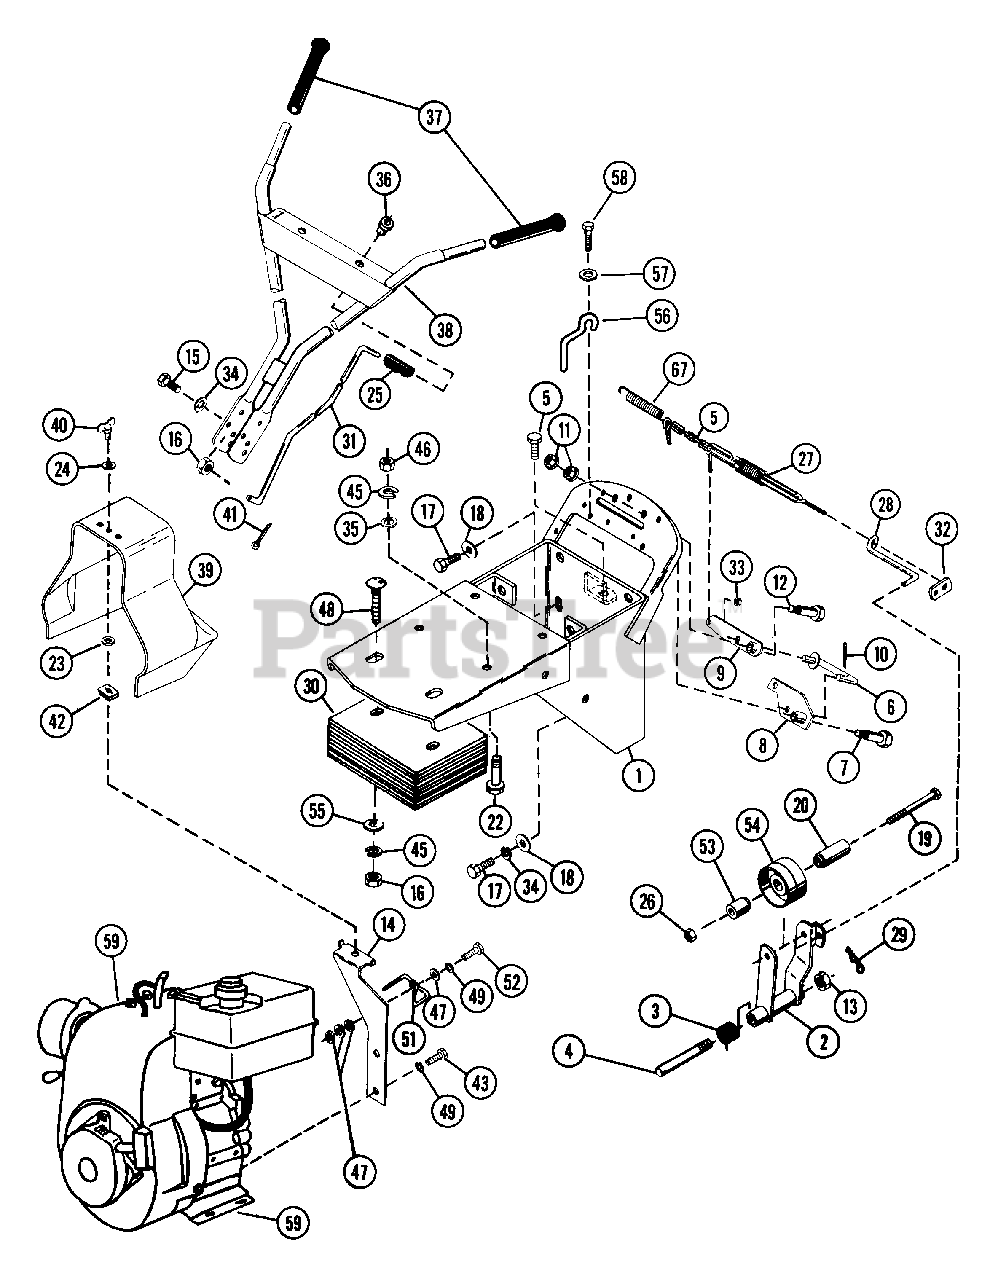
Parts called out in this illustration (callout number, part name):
2	IDLER ARM
3	SG-TORS .076X.89X1.98
4	IDLER PIN
5	BLT-HEX .31-18X1.00 PL GR 2
6	CLUTCH LINK
7	SHOULDER BOLT
8	CLUTCH BELLCRANK
9	SPRING ARM
10	PIN-COTR .09X1.0 PL
11	NUT-LK-CTR .375-16 GR A PL
12	SHOULDER BOLT
13	NUT-LK-FLG .375-16 PL
14	BELT COVER BRACKET
15	BLT-HEX .38-16X1.00 PL
16	NUT-HEX .375-16
17	BLT-HEX .38-16X1.25 PL GR 2
18	WSHR-FL-STL.406X.812X.065PL
19	BLT-HEX .31-18X3.75 PL GR2
20	SPACER-SHOULDER
22	BLT-HEX .31-18X1.00 PL GR 2
23	NUT-RETNR
24	WSHR-FL-STL .250X.562X.049 PL
25	GRIP
26	NUT-LK .312-18 GR A PL
27	CLUTCH SPRING
28	CLUTCH LINK
29	PIN-HAIR INT .06X.18X.77
30	WEIGHT WAFER
31	CLUTCH ROD
32	RETAINING NUT
33	NUT-LK 8-32 GR A PL
34	WSHR-LK .375X.115 HVY PL
35	WSHR-FL-STL .38X.875X.083 PL
36	SNAP BUSHING
37	HANDLEGRIP
38	HANDLEBAR
39	BELT COVER
40	SCR-WING .25 TURN SOUTHCO
41	PIN-COTR .09X.75 PL
42	NUT-SPEED 1/4 TURN SOUTHCO
43	BLT-HEX .31-24X.50 GR5
45	WSHR-LK .375X.094 MED PL
46	NUT-LK .312-18 GR A PL
47	WSHR-FL-STL .323X.625X.062 PL
48	BLT-RDHDSQNK .38-16X3.25 PL
49	WSHR-LK-INT .313X.030 PL
51	FORWARD BELT FINGER
52	BLT-HEX .31-24X1.00 PL GR5
53	SPACER .328X.625X.843
54	IDLER-FLAT 2.25 X .38
55	WSHR-FL-STL .630X1.005X.062 PL
56	BELT FINGER
57	WSHR-FL-STL .323X.625X.062 PL
58	SCR-TAP .250-20X.50 HXSLHDPL
59	ENGINE
